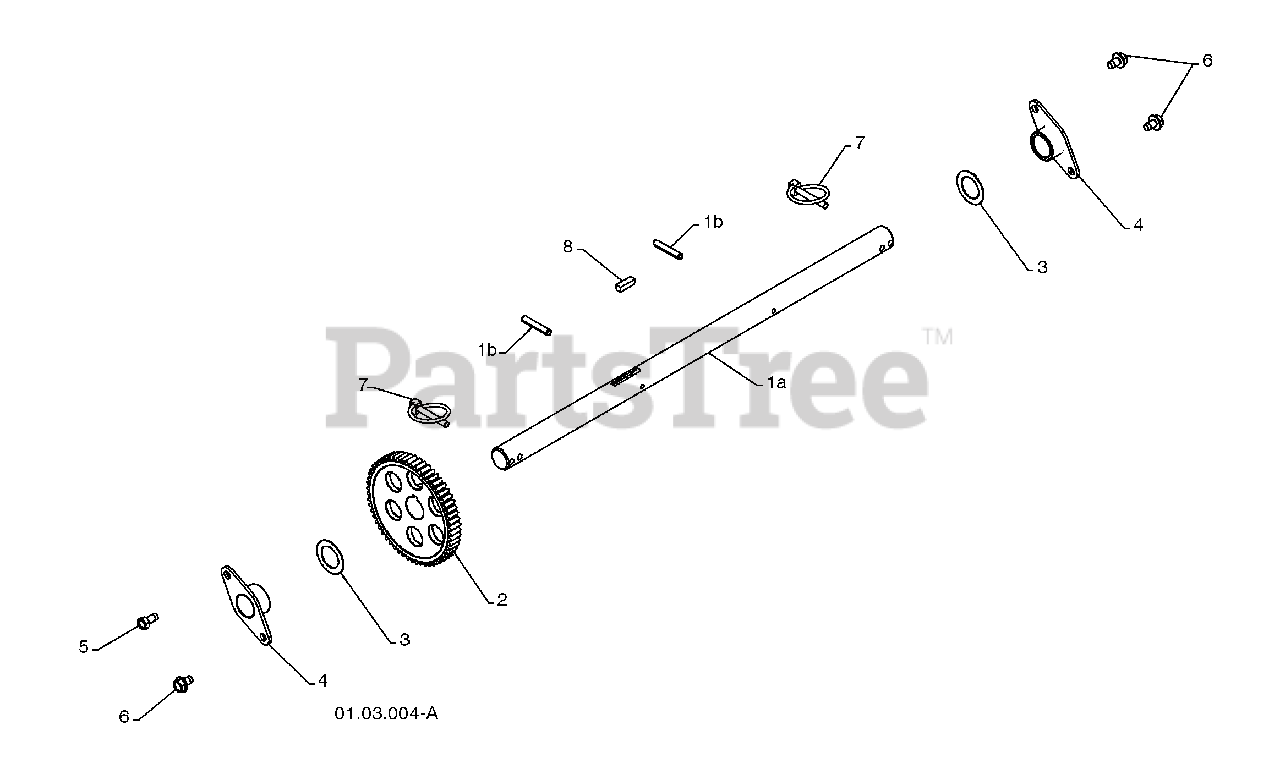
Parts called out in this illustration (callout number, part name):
1	AXLE ASSEMBLY
2	GEAR
3	THRUST WASHER
5	SCREW 5/16-18 X .625
6	BOLT 5/16-18 X .500
8	SQUARE KEY
